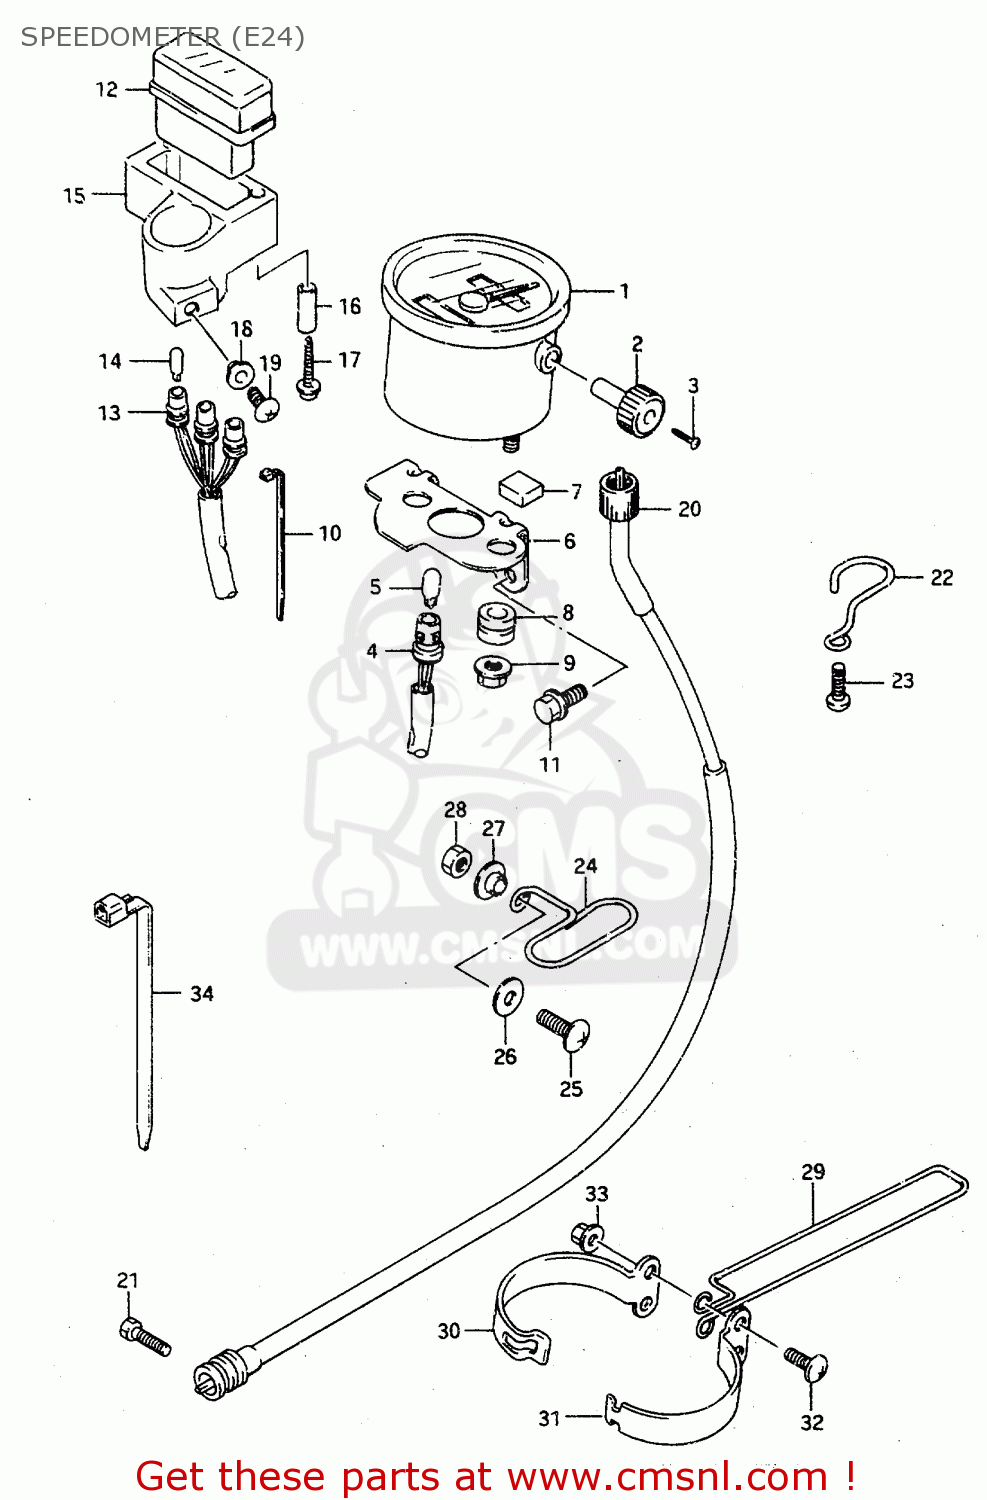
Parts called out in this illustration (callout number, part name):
1	SPEEDOMETER
2	KNOB,TRIP
3	SCREW,TRIP KNOB
4	SOCKET
5	BULB(12V3W,WB371,T7)
6	BRACKET,SPEEDOMETER
7	CUSHION
8	CUSHION
9	NUT
10	CLAMP
11	BOLT 6X12
12	BOX ASSY, PILOT LAMP
13	SOCKET
14	BULB(13.5V,2W,A7427)
15	HOLDER,PILOT BOX
16	SPACER (4.5X6.5X25)
17	SCREW
18	WASHER
19	SCREW 5X10
20	CABLE ASSY, SPEEDOMETER
21	BOLT
22	GUIDE,SPEEDOMETER CABLE
23	SCREW
24	GUIDE, CABLE NO.2
25	SCREW
26	WASHER
27	WASHER
28	NUT
29	GUIDE, CABLE NO.3
30	BRACKET,CABLE GUIDE
31	BRACKET,CABLE GUIDE
32	SCREW
33	NUT ,5MM
34	CLAMP(L:125)
